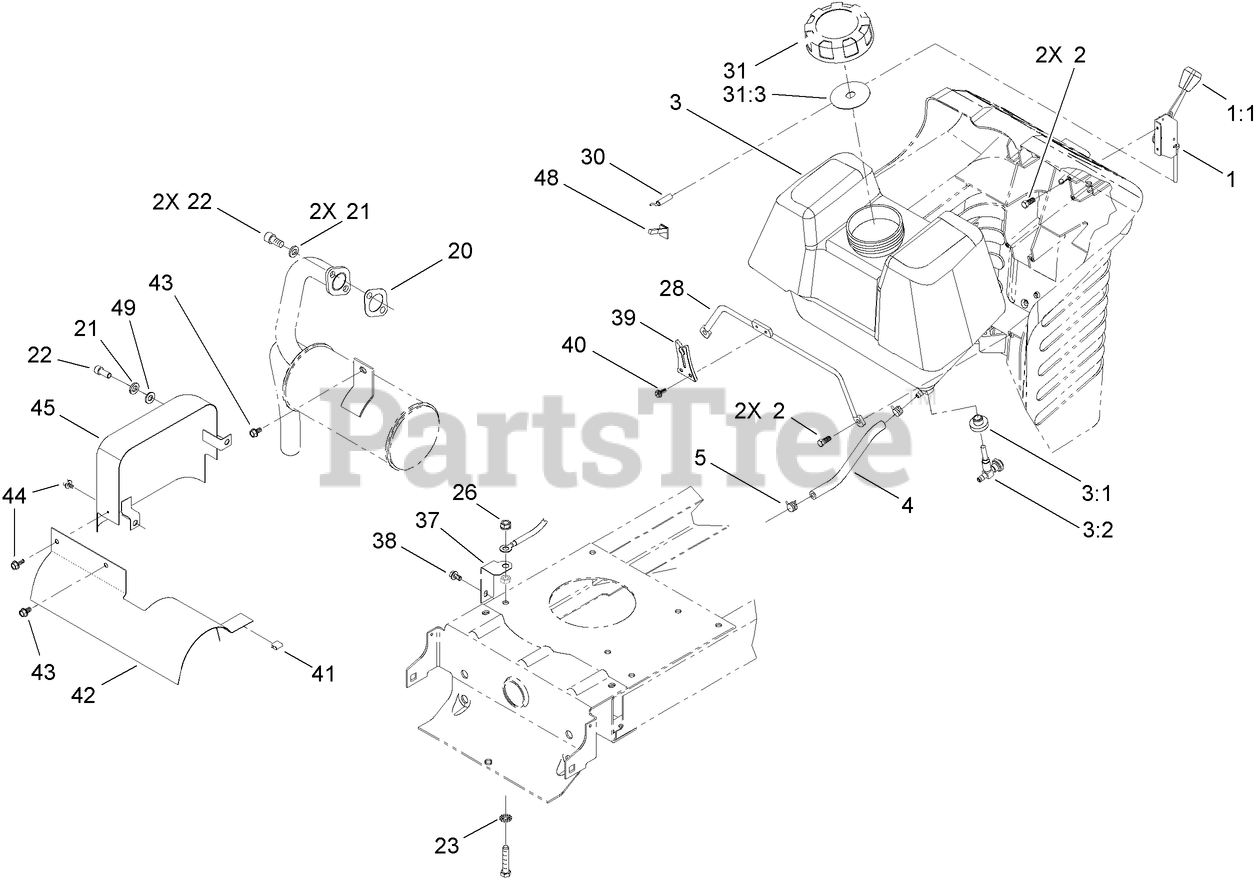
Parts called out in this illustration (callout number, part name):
1	THROTTLE CONTROL ASM
2	SCREW-SPECIAL
3	GAS TANK ASM
3:1	BUSHING
3:2	VALVE-FUEL
4	HOSE-FUEL
5	CLAMP-HOSE
20	GASKET-EXHAUST
21	WASHER-LOCK
22	SCREW-HSH
23	WASHER-LOCK
26	NUT-KEPS
28	ROD-TANK, GAS
30	THROTTLE CABLE ASM
31	GAS CAP ASM
31:3	GASKET-CAP, GAS
37	BRACKET-GROUND
38	SCREW-HWH
39	LATCH-HOOD
40	SCREW-HWH
41	CLIP-TINNERMAN
42	SHIELD-MUFFLER
43	SCREW-HWH
44	SCREW-HWHTF
45	HEAT SHIELD ASM
48	REDUCER-THROTTLE, RPM
49	WASHER-PLAIN
